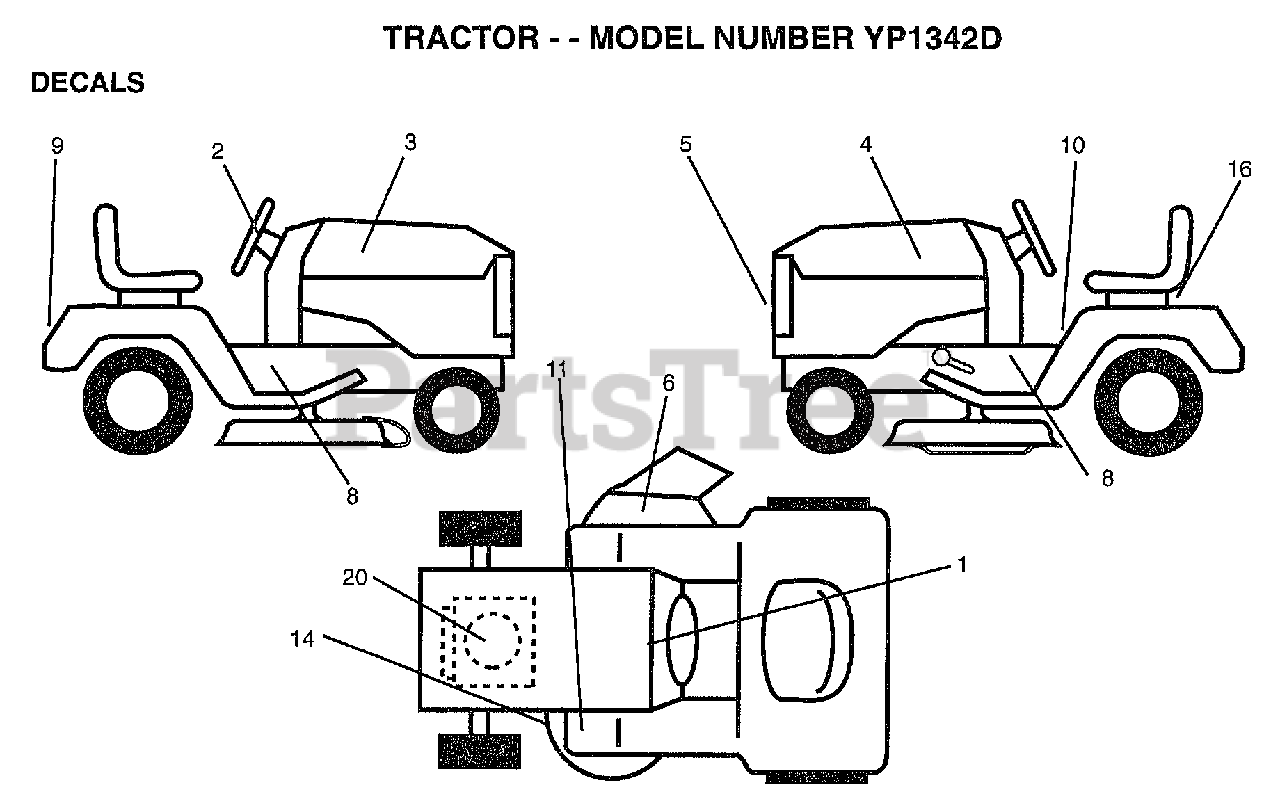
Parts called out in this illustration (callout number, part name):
1	"DECAL.OPER,SDL"
2	"DECAL INSERT,STRG"
3	DECAL.HOOD.RH
4	DECAL HOOD LH
6	"DECAL, WARNING"
8	DECAL CHASSIS
9	DECAL FENDER
10	DECAL.CAUT.ENG/FR
11	DECAL T
14	"DECAL-SCHEM,BELT"
16	DECAL.BATRY.3-3908
20	DECAL HP ENGINE
